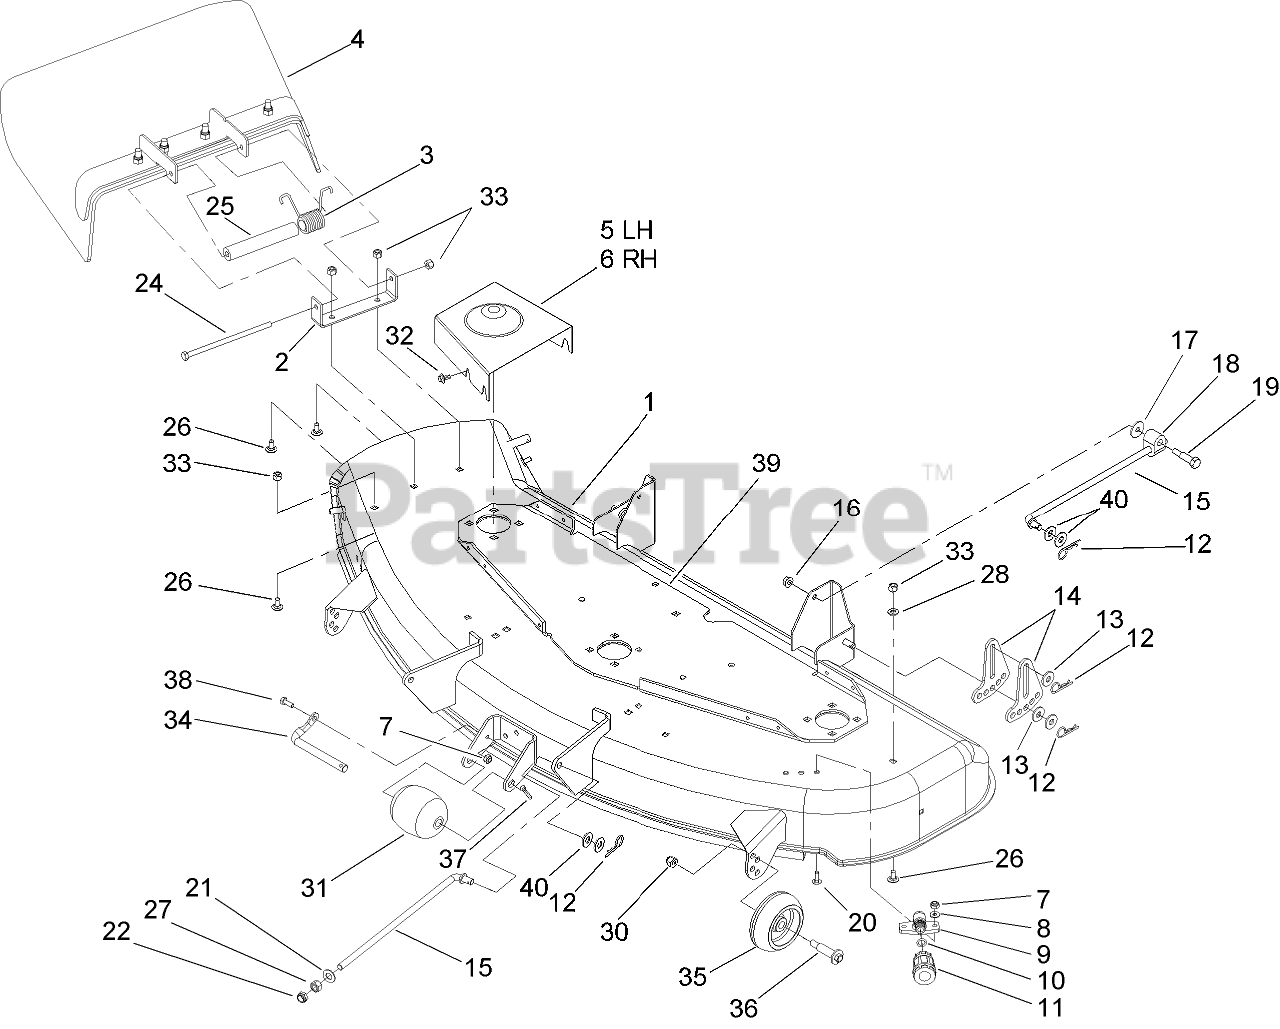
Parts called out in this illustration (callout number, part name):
1	48 INCH DECK ASM
2	BRACKET-PIVOT
3	SPRING-TORSION
4	DEFLECTOR ASM
5	COVER-BELT, LH
6	COVER-BELT, RH
7	NUT-LOCK, NI
8	WASHER-FLAT
9	FITTING-WASHOUT
10	O-RING
11	CONNECTOR-HOSE
12	PIN-HAIR
13	WASHER-HARDENED
14	LINK-ADJUSTING, HOC
15	ROD-HANGER
16	NUT-HF
17	WASHER-PIVOT
18	TRUNNION-HOC
19	SCREW-SHOULDER, HH
20	BOLT-CARR
21	WASHER-FLAT
22	NUT-LOCK, NI
24	BOLT-HH
25	SPACER-DEFLECTOR
26	SCREW-CARR
27	NUT-HEX
28	WASHER-PLAIN
30	NUT-LOCK, NI
31	ROLLER
32	SCREW-HHFTF
33	NUT-LOCK, NI
34	ROLLER-SHAFT
35	WHEEL-GAGE
36	SCREW-SHOULDER, HWH
37	PIN-COTTER
38	SCREW-HH
39	PLATE-REINFORCEMENT, DECK
40	WASHER-FLAT
